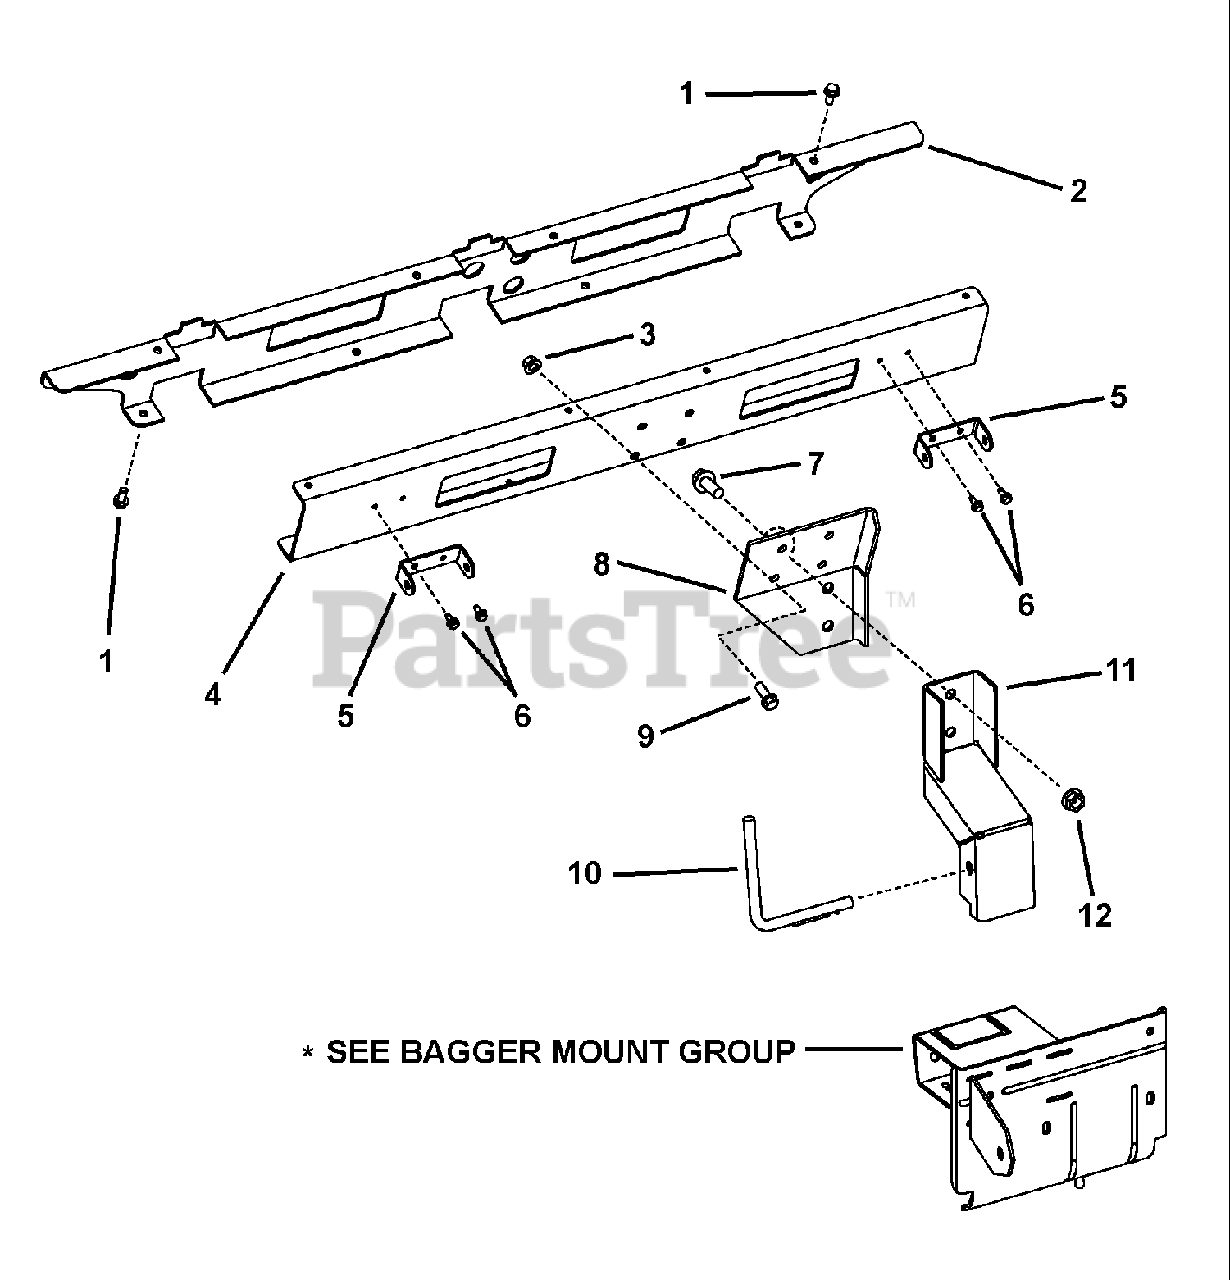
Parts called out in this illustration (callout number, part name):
1	SCREW, HWH TAPTITE 5/16-18 X 3/4" BLACK
2	BRACKET, TAB CROSS SUPPORT, TRIPLE GRASS CATCHER
3	NUT, HEX FLNG WHIZ LK 3/8-16
4	CHANNEL, CROSS SUPPORT, TRIPLE GRASS CATCHER
5	PIVOT, HINGE
6	HWHS, TAPTITE 1/4-20 X .500 BLK
7	HFLB, 1/2-13 X 1-1/4 GR5 YZ
8	PLATE, SUPPORT, TRIPLE GRASS CATCHER
9	SCREW, HEX WZ LOCK FLNG 3/8-16 WHIZ LK LARGE
10	PIN, CHANNEL MTG, GRASS CATCHER
11	ARM, SUPPORT, TRIPLE GRASS CATCHER
12	HFLN, 1/2-13-YZ
